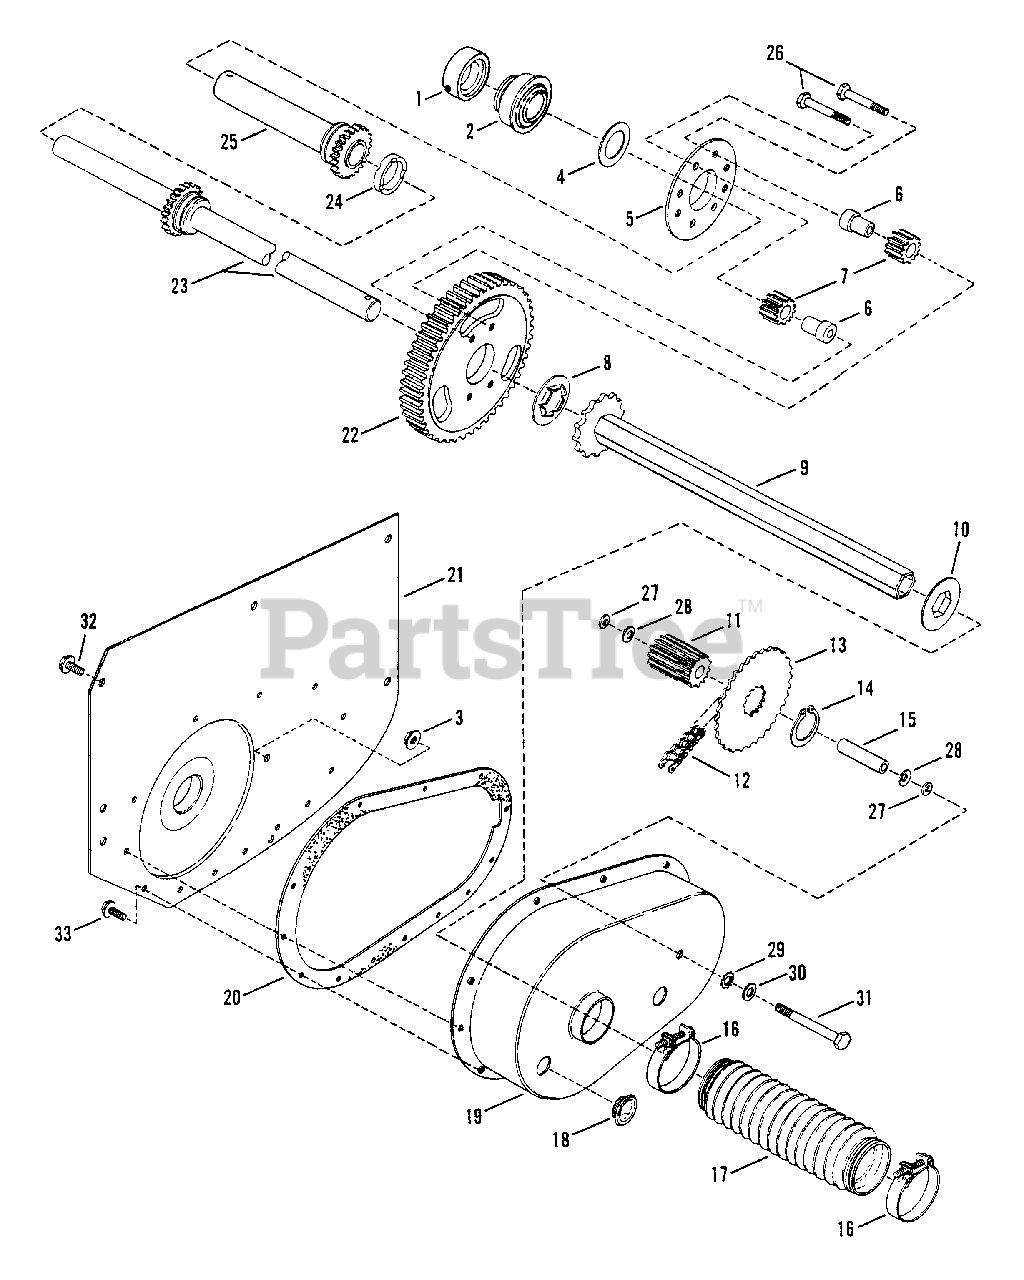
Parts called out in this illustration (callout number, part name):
1	COLLAR, Lock
2	BALL BEARING, Axle (Right Hand Fender)
3	NUT, 5/16-24 Hex Flange Lock
4	WASHER, Thrust
5	PLATE, Differential
6	SPACER, Pinion
7	GEARS, Differential Pinion
8	WASHER, Thrust
9	ASSEMBLY, Drive Hex Tube
10	WASHER, Hex Insert
11	GEAR, 11 Teeth-10 Pitch
12	CHAIN, 46 Pitch (#35)
13	SPROCKET
14	RING, External Retaining
15	SPACER
16	CLAMP, Boot
17	BOOT, Oil Seal
18	PLUG, Oil Fill & Check
19	CASE, Transmission
20	GASKET, Transmission Case
21	FENDER, Right Hand BB (2.498" Hole)
22	GEAR, 63 Teeth-10 Pitch
23	AXLE, Long
24	SPACER, Differential (1.25" ID x .425 Wide)
25	AXLE, Short
26	SCREW, 5/16-24 x 1-5/8" Hex Cap Special Lock
27	O-RING, 5/16"
28	WASHER, 5/16" Belleville
29	WASHER, 5/16" External Tooth Lock
30	WASHER, 5/16" Flat
31	BOLT, 5/16-24 x 2-5/8" Idler
32	SCREW, 5/16-18 x 5/8" Self-Tapping
33	SCREW, 1/4-20 x 5/8" Self-Tapping
